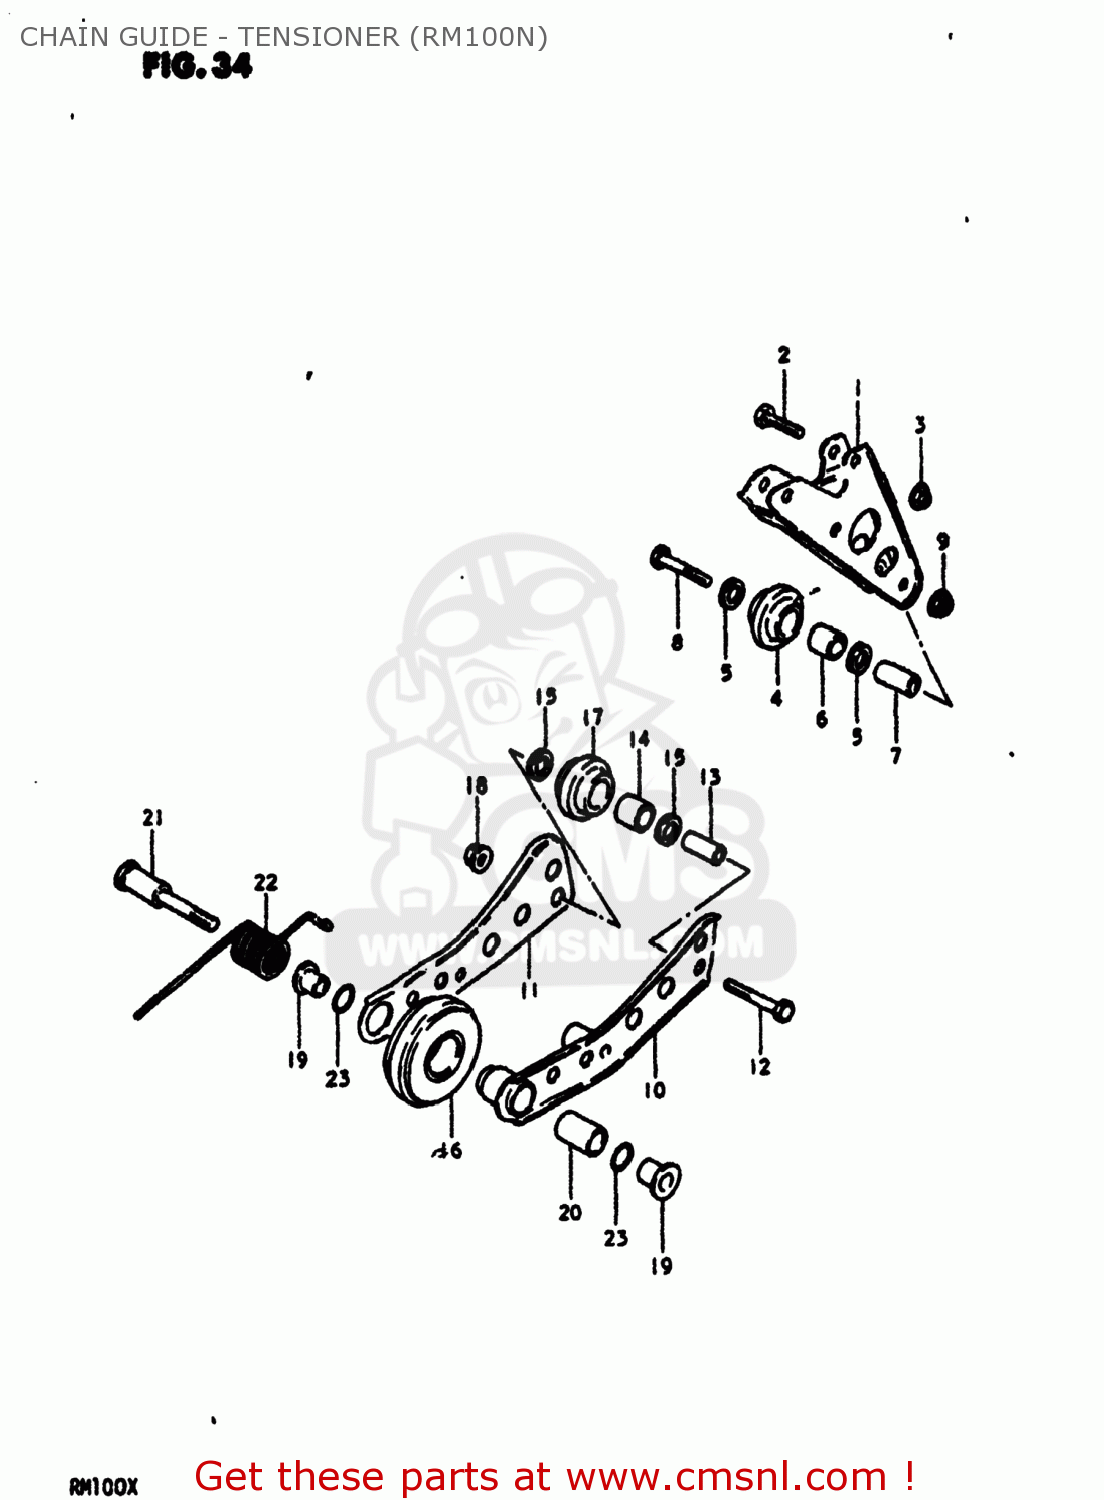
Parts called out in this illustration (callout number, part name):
1	GUIDE,DRIVE CHAIN
2	BOLT
3	NUT 6MM
4	ROLLER,CHAIN TENSIONER LWR
5	SEAL,OIL(10X14.4X3.5)
6	SPACER,CHAIN GUIDE
7	SPACER(6.2X10X22.5)
8	BOLT 6X35
9	NUT
10	TENSIONER,CHAIN
11	PLATE,CHAIN TENSIONER
12	BOLT 6X35
13	SPACER(6.2X10X22.5)
14	SPACER,CHAIN GUIDE
15	SEAL,OIL(10X14.4X3.5)
16	ROLLER,CHAIN GUIDE
17	ROLLER,CHAIN TENSIONER LWR
18	NUT
19	SPACER,CHAIN TENSIONER
20	BUSHING,CHAIN TENSIONER
21	BOLT
22	SPRING
23	O RING(D:1.3,ID:9.6)
